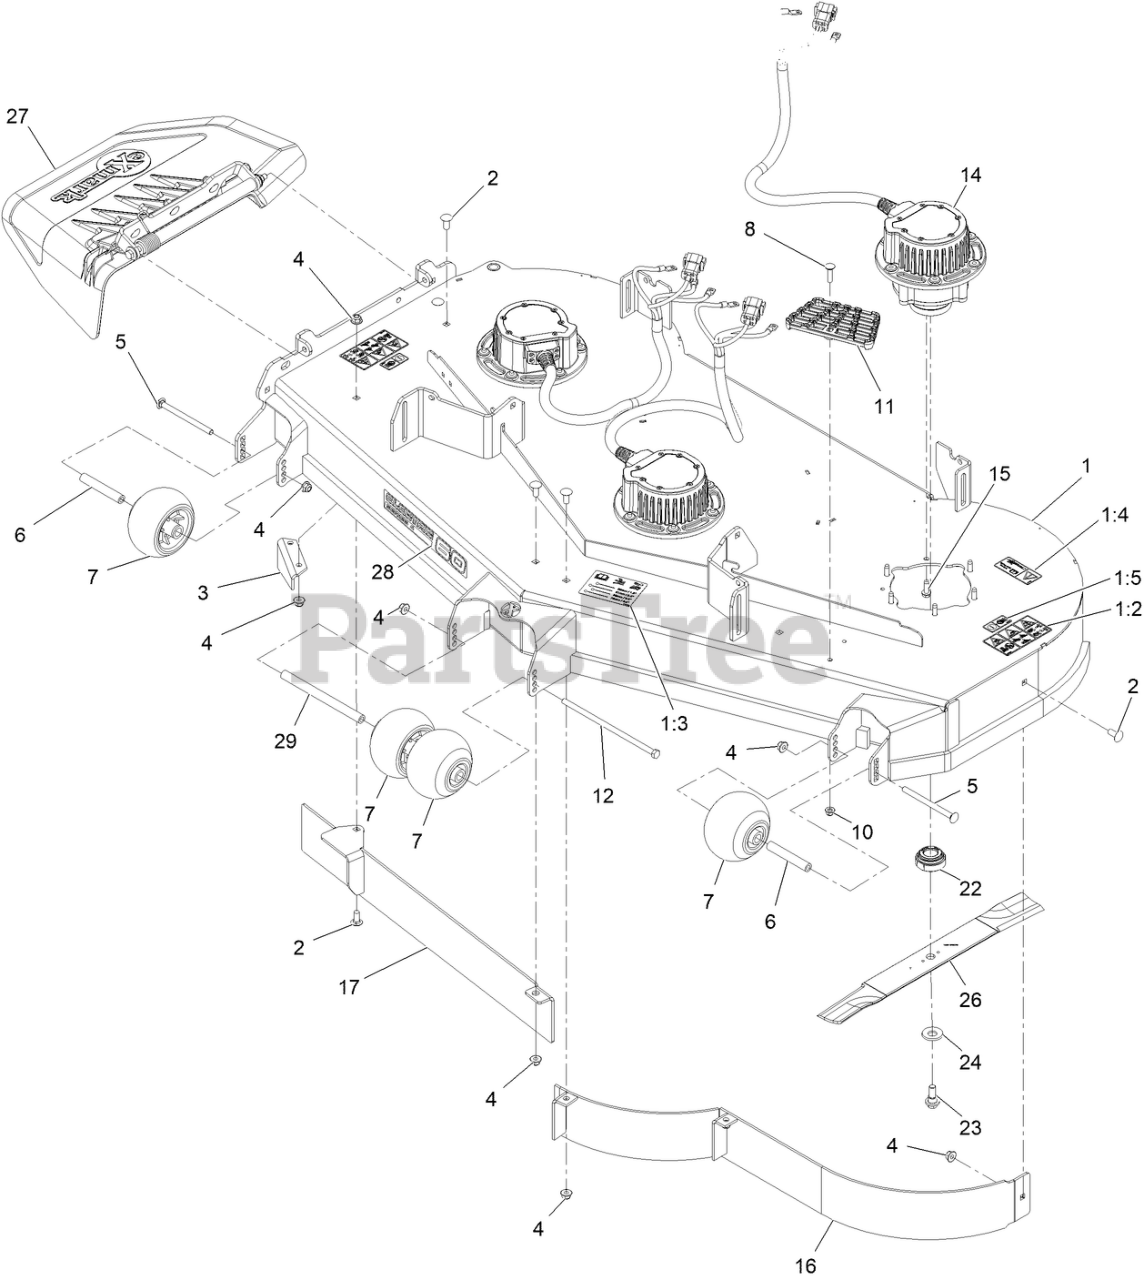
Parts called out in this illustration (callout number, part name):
1	ASM, Deck W/ Decals, 60
1:2	DECAL-DANGER
1:3	DECAL-SCALP, ANTI
1:4	DECAL-DANGER
1:5	DECAL-NO SPRAY
2	SCREW-CARR
3	BAFFLE-DISCHARGE
4	NUT-HF, NI
5	BOLT-CARR
6	SPACER-AXLE
7	ROLLER-SCALP, ANTI
8	Bolt-Carriage 5/16-18 X 1 1/4
10	NUT-HF, NI
11	STEP-DECK
12	SCREW-HH
14	MOTOR/GEN
15	SCREW-THD ROLL, HWH
17	Baffle-Front, 60 [red]
22	RETAINER-BLADE
23	SCREW-SHOULDER, HWH
24	Washer-Belleville
26	BLADE-20.5IN, MED SAIL
27	ASM- DISCHARGE CHUTE
28	DECAL-ELECTRIC 60 SERIES 4
29	SPACER-AXLE, DOUBLE
